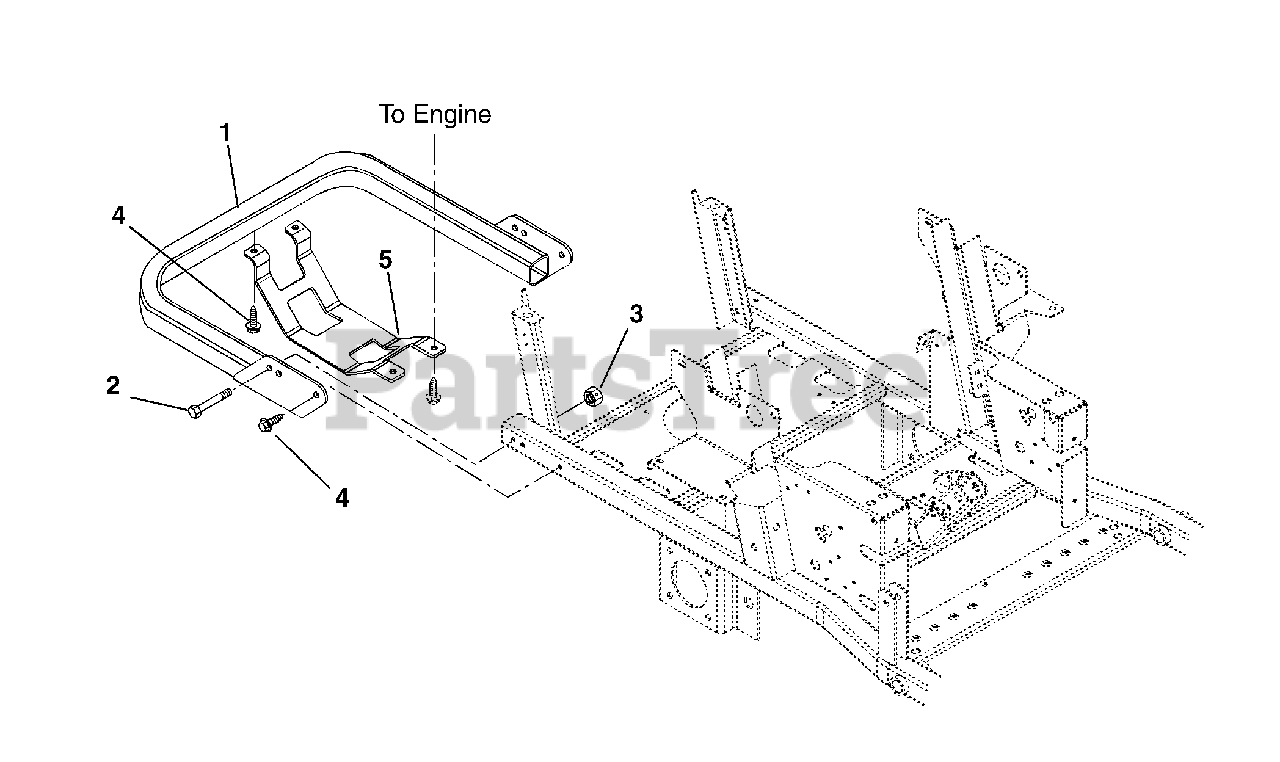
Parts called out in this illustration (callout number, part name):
1	Bumper-Rear
2	Bolt-Hex .38-16 x 2.75 Grade 5
3	Nut-Locking-Center .38-16
4	Screw-Tapping .38-16 x .75 Hex Washer Head
5	Plate, Skid PM250Z
